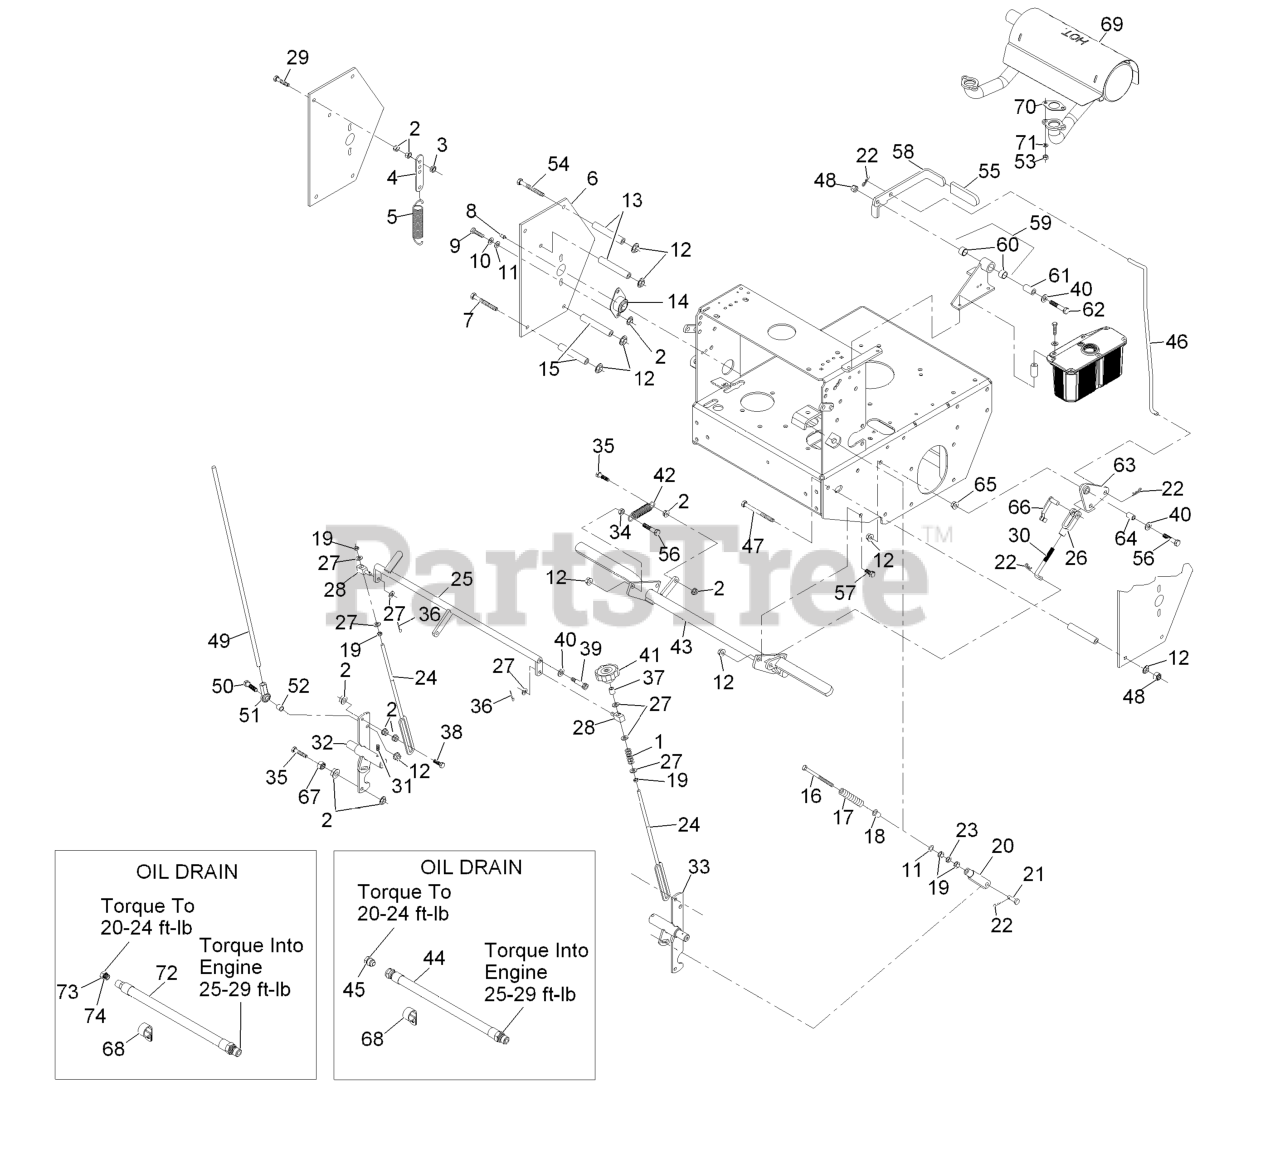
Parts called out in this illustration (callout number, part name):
1	SPRING-COMPRESSION
3	NUT-LOCK, NI
4	TAB-SPRING, EXTENSION
5	SPRING-EXTENSION
6	SHIELD-CONTROL
7	SCREW-HH
8	FITTING-GREASE
9	SCREW-HH
10	WASHER-LOCK
11	WASHER-FLAT
12	NUT-HHF, WHIZ
13	SPACER-SHIELD
14	BEARING-FLANGE, SIDE
15	SPACER-SHIELD
16	BOLT-RETURN, NEUTRAL
17	SPRING,COMPRESSION (NEUT)
18	BUSHING-FLANGED
19	NUT-HEX
20	YOKE-ADJUSTABLE
21	PIN-CLEVIS
22	PIN-COTTER
23	NUT-JAM
24	LINK-CONTROL, SPEED
25	CRANK-CONTROL, SPEED
26	YOKE-LINKAGE, BRAKE
27	WASHER-PLAIN
29	BOLT-TAP, HH
30	LINKAGE-LOWER
31	SCREW-SET
32	SHAFT-CONTROL, LH
33	SHAFT-CONTROL, RH
34	NUT-JAM
35	SCREW-HH, SPECIAL
36	PIN-COTTER
38	SCREW-HH
39	SCREW-HSH
40	WASHER-FLAT
41	KNOB-TRACKING
42	SPRING-IDLER
46	LINKAGE,UPPER- TTHP
47	SCREW-HH
48	NUT-LOCK, NI
49	LINK,DRIVE (PLTD)
50	SCREW-HH
51	JOINT-BALL END, LH
52	SPACER-TUBE, PUMP LINK
54	SCREW-HH
55	GRIP-LEVER
56	SCREW-HH
57	SCREW-HH
58	LEVER,PARK BRK W/DECAL
59	BRACKET ASM
60	SLEEVE-BUSHING
61	BUSHING-PIVOT
62	SCREW-HH
63	BELLCRANK ASM
64	BUSHING-PLASTIC
66	PIN-SPRING, CLEVIS
67	NUT-JAM
68	CLIP-LOOM
69	MUFFLER,HORIZONTAL
70	GASKET-EXHAUST
71	WASHER-LOCK
72	ASM, ENGINE OIL DRAIN HOS
73	PLUG-HH
74	O-RING
